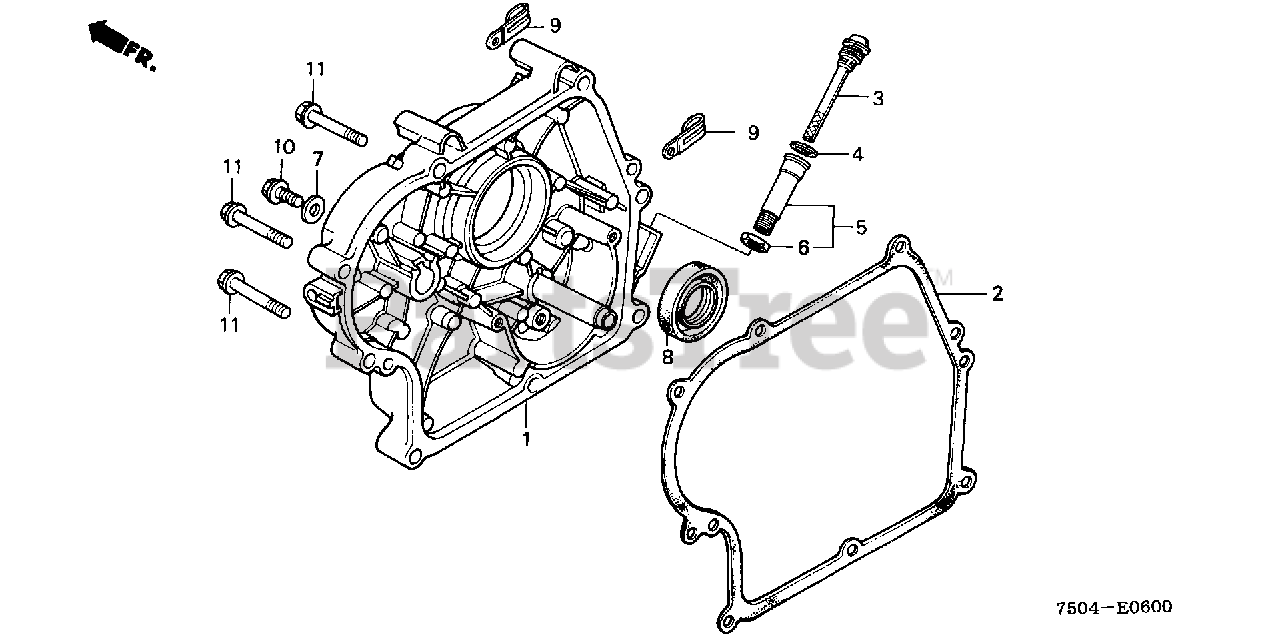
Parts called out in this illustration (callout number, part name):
1	COVER, CRANKCASE
2	GASKET, CASE COVER
3	CAP, OIL FILLER
4	GASKET, OIL FILLER CAP
6	NUT, OIL FILLER
7	WASHER A (8MM)
8	OIL SEAL (30X46X8)
9	CLIP, WIRE HARNESS
10	BOLT, FLANGE (8X12)
11	BOLT, FLANGE (8X45)
11	BOLT, FLANGE (8X45) (DENSO)
